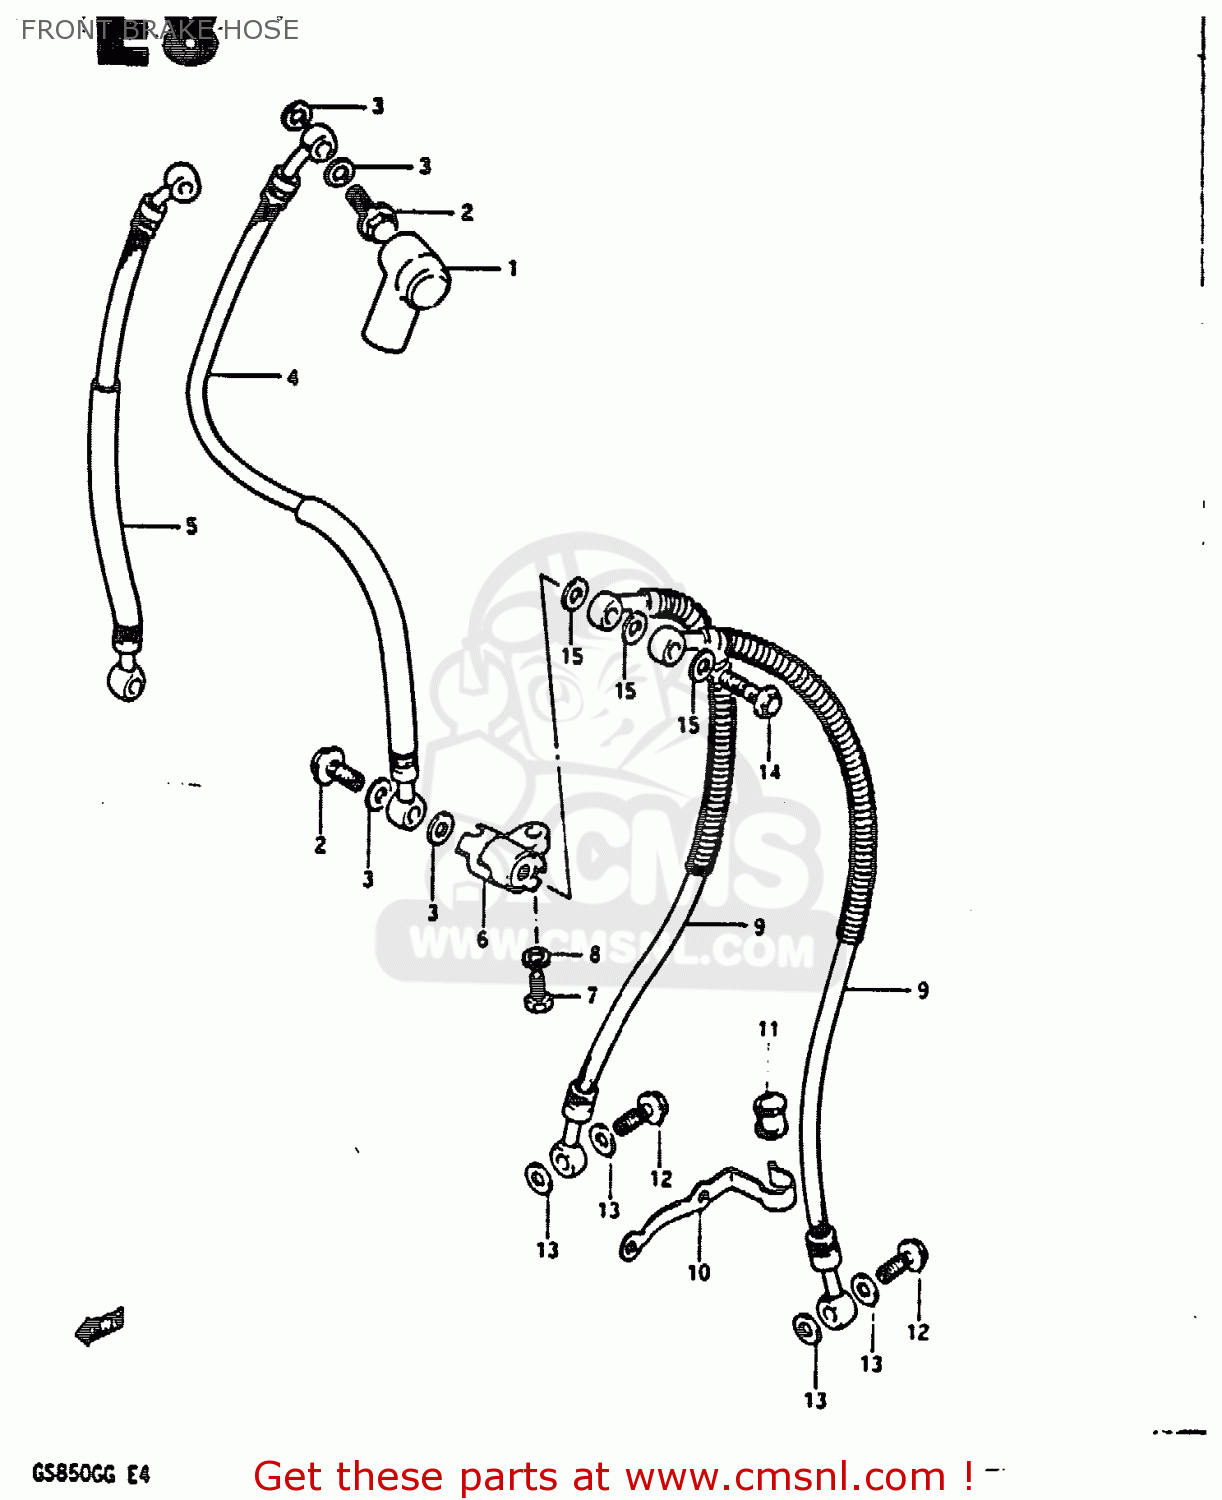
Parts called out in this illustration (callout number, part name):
1	BOOT,MASTER CYLINDER
2	BOLT UNION
3	WASHER(10X15X1.5)
4	HOSE,BRAKE NO.1
5	HOSE, BRAKE NO.1 (L:390)
6	JOINT,BRAKE HOSE
7	BOLT
8	WASHER,LOCK
9	HOSE,FRONT BRAKE
10	GUIDE,BRAKE HOSE NO.2
11	BUSH,BRAKE HOSE GUIDE,NO.2
12	BOLT UNION
13	WASHER(10X15X1.5)
14	BOLT UNION
15	WASHER(10X15X1.5)
